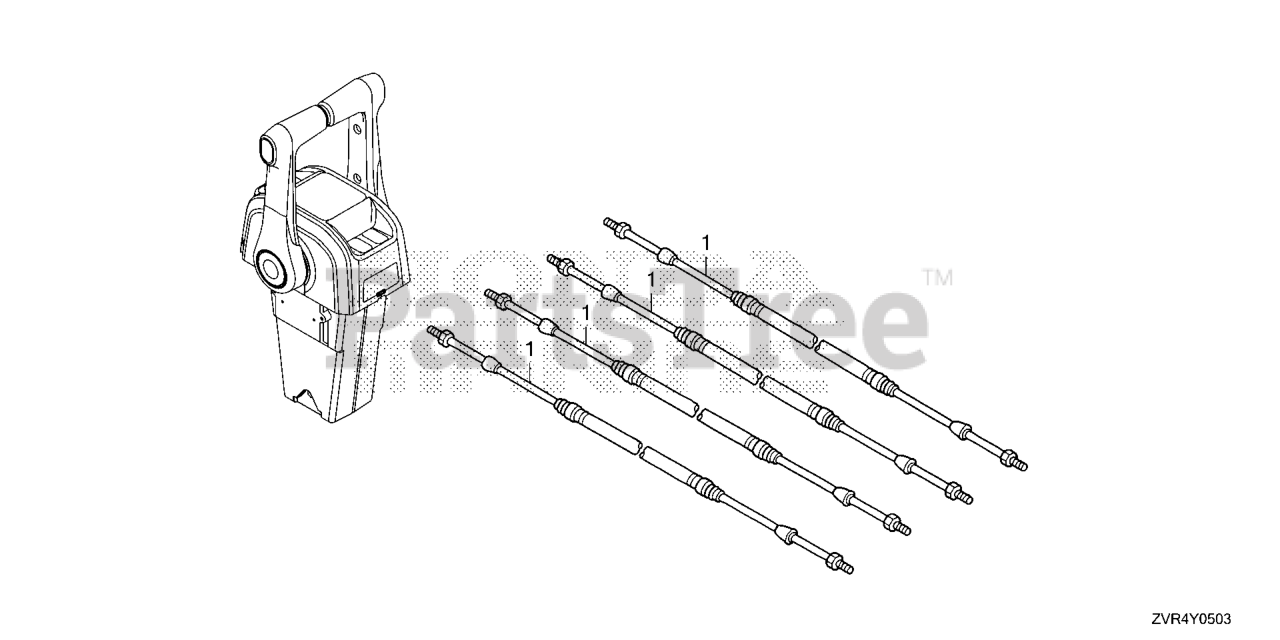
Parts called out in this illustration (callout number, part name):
1	CABLE ASSY., PUSH-PULL (33HPC-5FT)
1	CABLE ASSY., PUSH-PULL (33HPC-6FT)
1	CABLE ASSY., PUSH-PULL (33HPC-7FT)
1	CABLE ASSY., PUSH-PULL (33HPC-8FT)
1	CABLE ASSY., PUSH-PULL (33HPC-9FT)
1	CABLE ASSY., PUSH-PULL (33HPC-10FT)
1	CABLE ASSY., PUSH-PULL (33HPC-11FT)
1	CABLE ASSY., PUSH-PULL (33HPC-12FT)
1	CABLE ASSY., PUSH-PULL (33HPC-13FT)
1	CABLE ASSY., PUSH-PULL (33HPC-14FT)
1	CABLE ASSY., PUSH-PULL (33HPC-15FT)
1	CABLE ASSY., PUSH-PULL (33HPC-16FT)
1	CABLE ASSY., PUSH-PULL (33HPC-17FT)
1	CABLE ASSY., PUSH-PULL (33HPC-18FT)
1	CABLE ASSY., PUSH-PULL (33HPC-19FT)
1	CABLE ASSY., PUSH-PULL (33HPC-20FT)
1	CABLE ASSY., PUSH-PULL (33HPC-21FT)
1	CABLE ASSY., PUSH-PULL (33HPC-22FT)
1	CABLE ASSY., PUSH-PULL (33HPC-23FT)
1	CABLE ASSY., PUSH-PULL (33HPC-24FT)
1	CABLE ASSY., PUSH-PULL (33HPC-25FT)
1	CABLE ASSY., PUSH-PULL (33HPC-26FT)
1	CABLE ASSY., PUSH-PULL (33HPC-27FT)
1	CABLE ASSY., PUSH-PULL (33HPC-28FT)
1	CABLE ASSY., PUSH-PULL (33HPC-29FT)
1	CABLE ASSY., PUSH-PULL (33HPC-30FT)
1	CABLE ASSY., PUSH-PULL (33HPC-31FT)
1	CABLE ASSY., PUSH-PULL (33HPC-32FT)
1	CABLE ASSY., PUSH-PULL (33HPC-33FT)
1	CABLE ASSY., PUSH-PULL (33HPC-34FT)
1	CABLE ASSY., PUSH-PULL (33HPC-35FT)
1	CABLE ASSY., PUSH-PULL (33HPC-36FT)
1	CABLE ASSY., PUSH-PULL (33HPC-37FT)
1	CABLE ASSY., PUSH-PULL (33HPC-38FT)
1	CABLE ASSY., PUSH-PULL (33HPC-39FT)
1	CABLE ASSY., PUSH-PULL (33HPC-40FT)
